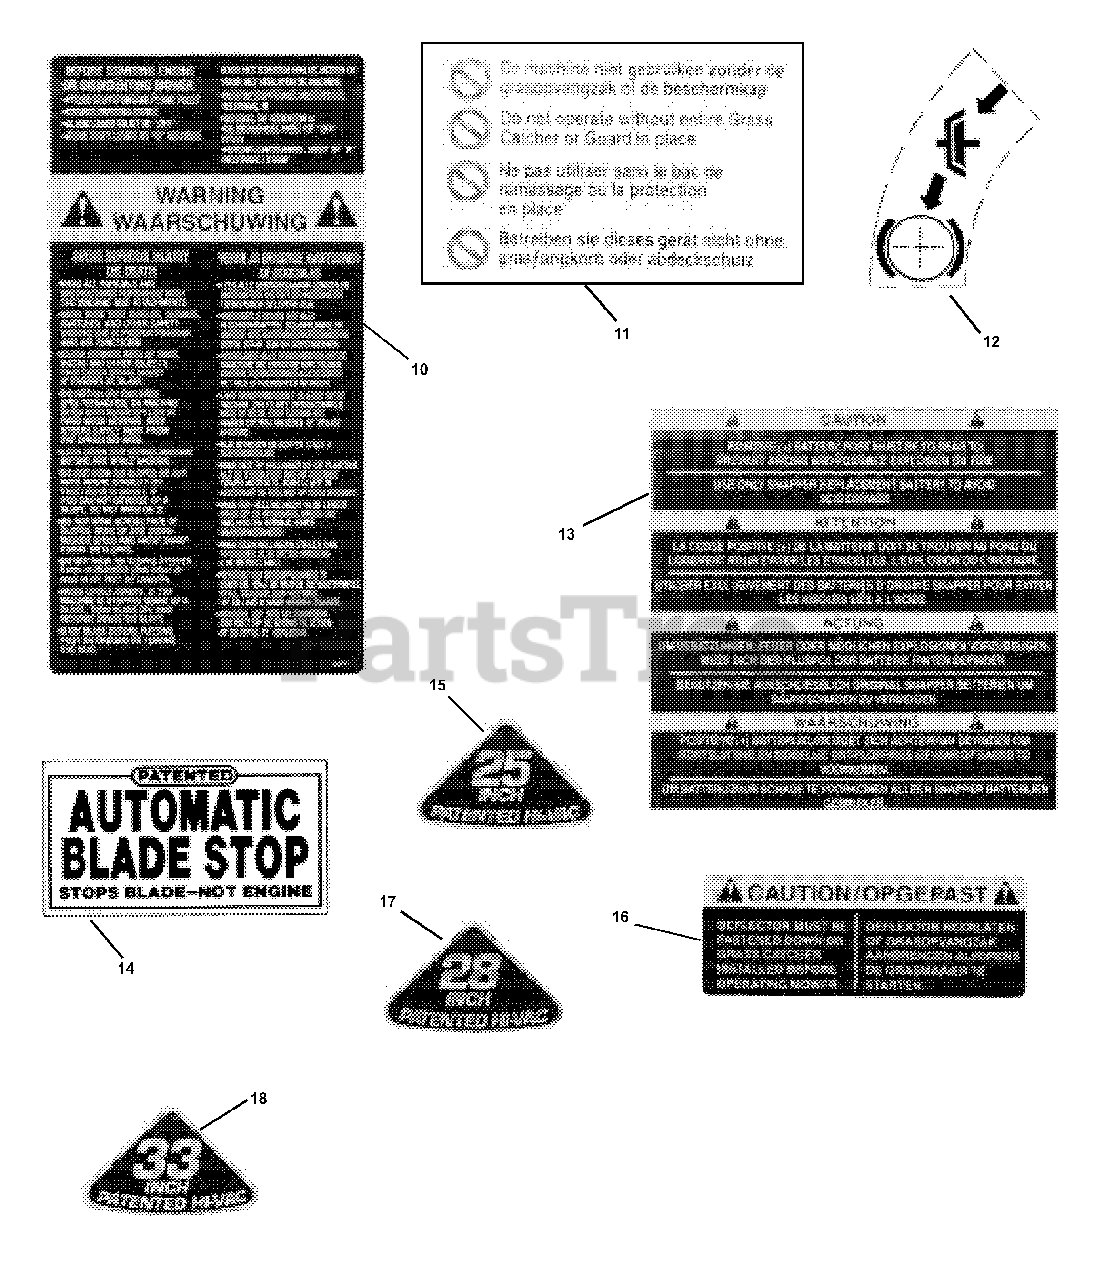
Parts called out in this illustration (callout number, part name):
10	DECAL, SAFETY Instruction (English & Dutch)
11	DECAL, DO NOT OPERATE!
12	DECAL, Clutch/Brake
13	DECAL, Battery CAUTION
14	DECAL, Automatic Blade Stop
15	DECAL, 25 Inch (Hi-Vac)
16	DECAL, Deflector CAUTION (English & Dutch)
17	DECAL, 28 Inch (Hi-Vac)
18	DECAL, 33 Inch (Hi-Vac)
